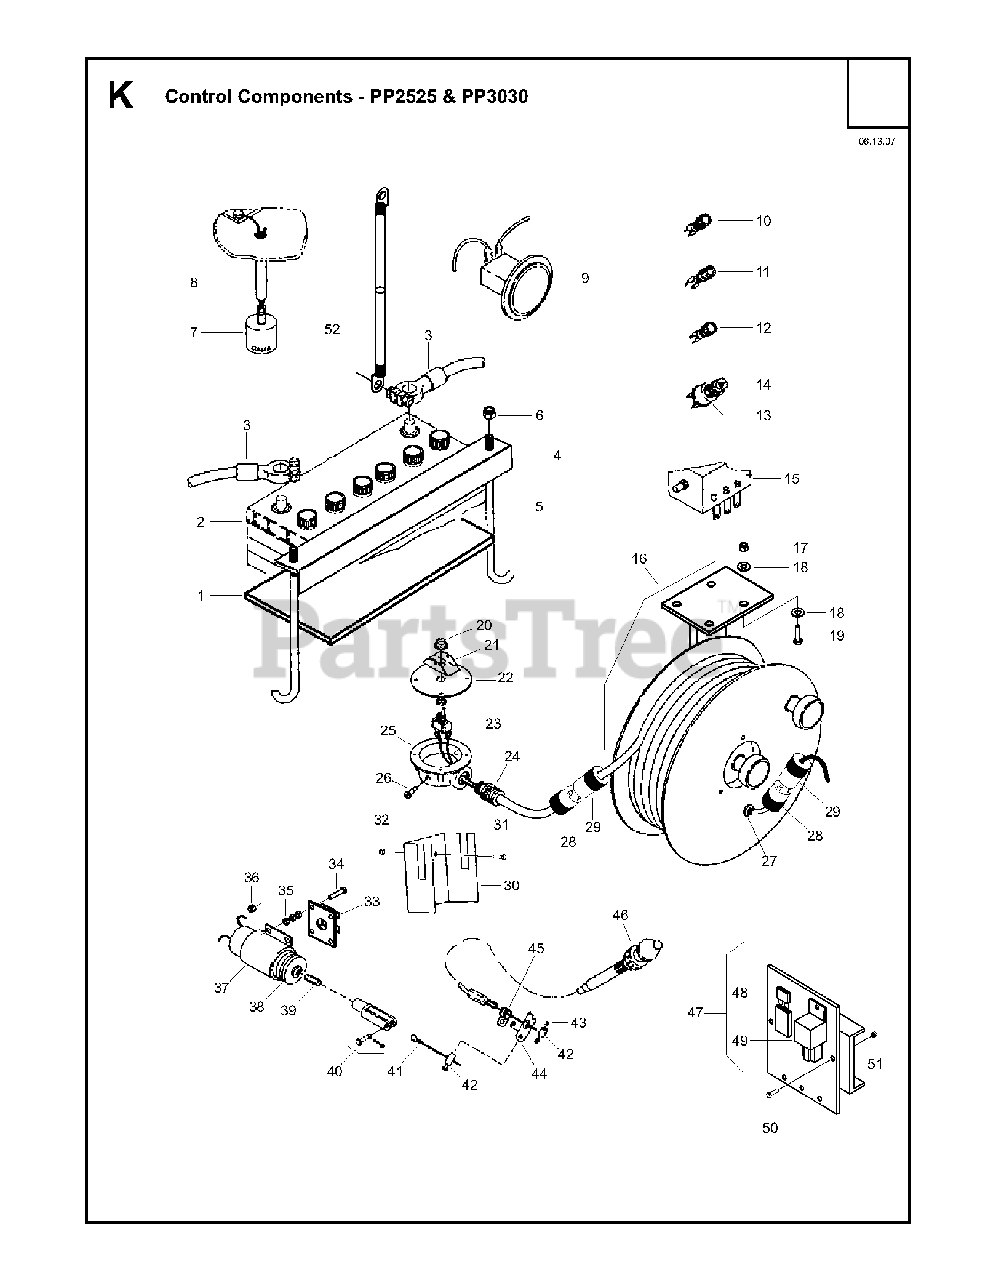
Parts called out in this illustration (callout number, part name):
3	CABLEQty 1 with Trailer Mounted
6	NUT
10	LIGHTEngine Temperature
11	OIL COOLEROil Pressure
17	NUT
33	PLATEMounting to Engine
36	NUT
48	CIRCUIT BREAKER. 10AMP
49	RELAY
51	LOCKNUT. FIBER 10-24
52	CABLEQty 2 Required for Trailer Mtg
